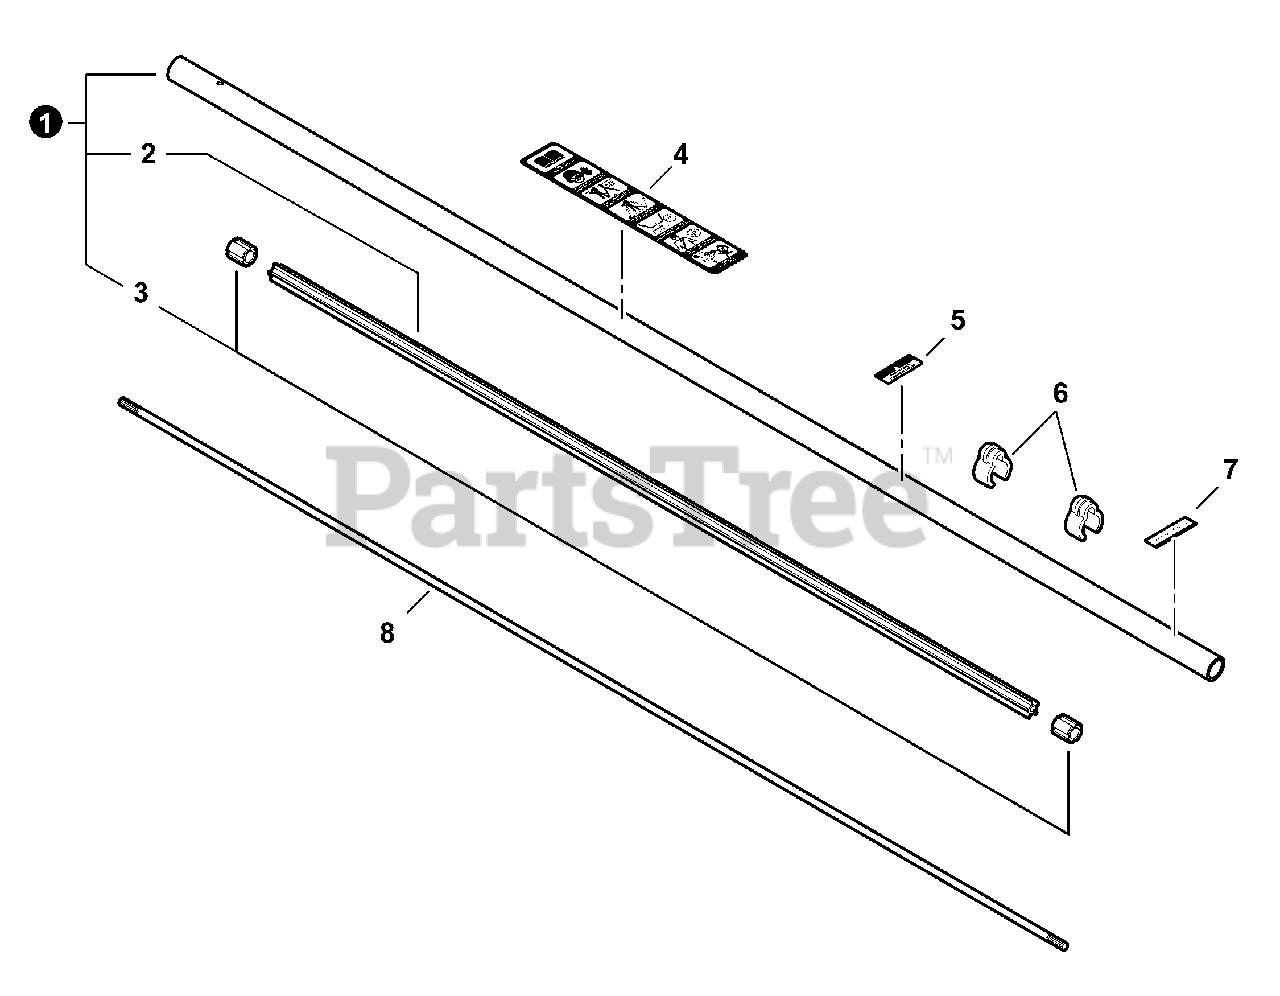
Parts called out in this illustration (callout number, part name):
1	MAIN PIPE ASSY
2	LINER, FLEXIBLE 21.6×1420
4	LABEL, CAUTION (BLADE CAPABLE)
5	LABEL, HANDLE
6	CLIP, CABLE 25MM
7	LABEL - ALIGNMENT
8	DRIVESHAFT - FLEXIBLE
